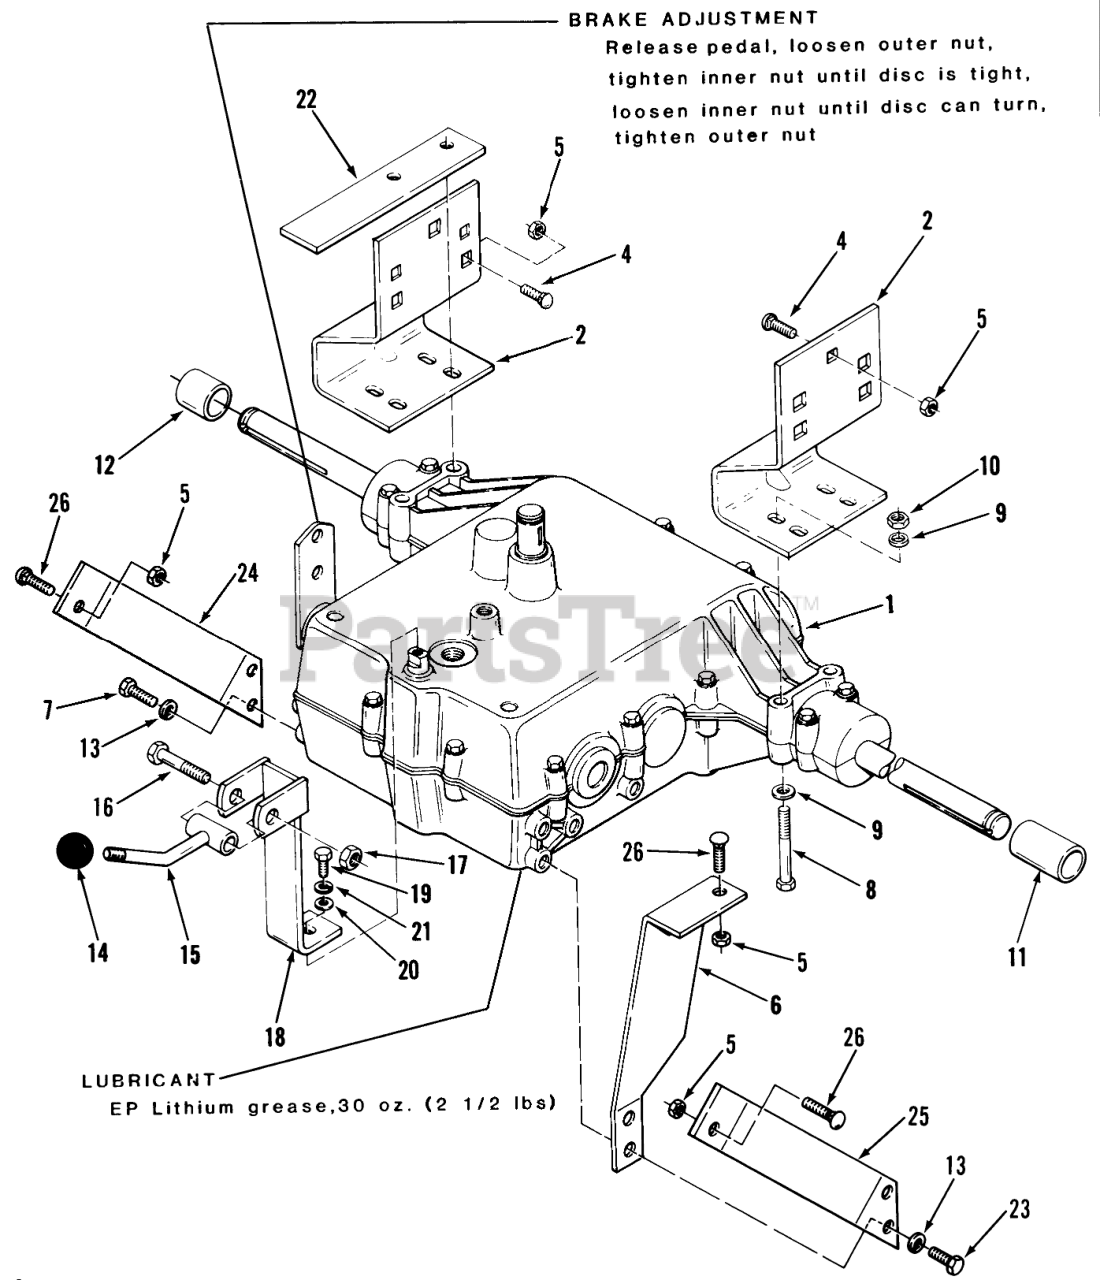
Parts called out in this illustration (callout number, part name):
1	Transmission-Peerless Model 822
2	BRKT-TRANS MOUNT R
4	CARRIAGE BOLT -4
5	Nut
6	TORQUE STRAP
7	Screw
8	HHCS
9	WASHER 5/16 SAE
10	Nut
11	SPACER-AXLE LH
12	SPACER-AXLE RH
13	Lockwasher
15	ASSY-UPPER SHIFT ROD
16	Bolt
17	Nut
18	ASSY LEVER R
19	Bolt 1/4-28 X 7/8
20	WASHER
21	Washer
22	Brake Stop Bar
23	Bolt
24	TORQUE STRAP RH
25	TORQUE STRAP LH
26	Bolt
